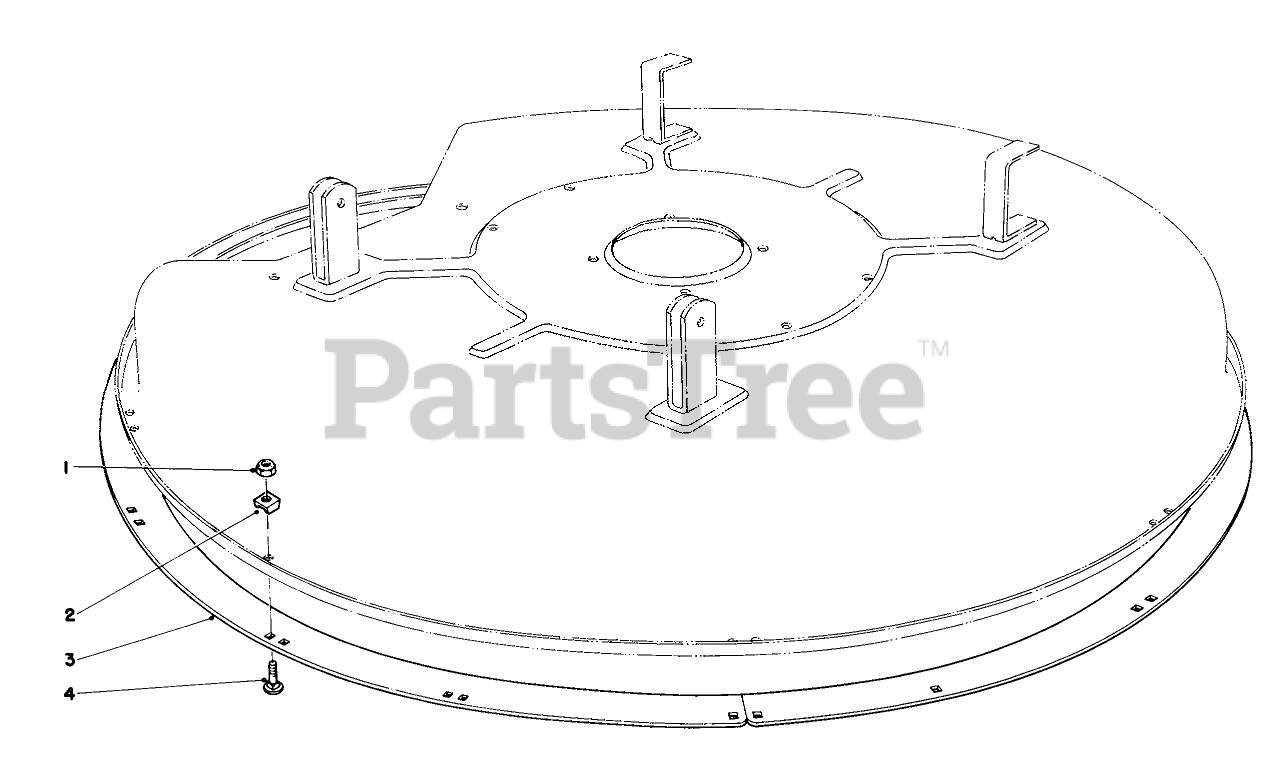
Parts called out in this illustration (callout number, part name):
1	NUT-LOCK, NI
2	DECK RING SPACER
3	DECK RING B
4	BOLT-CARR
